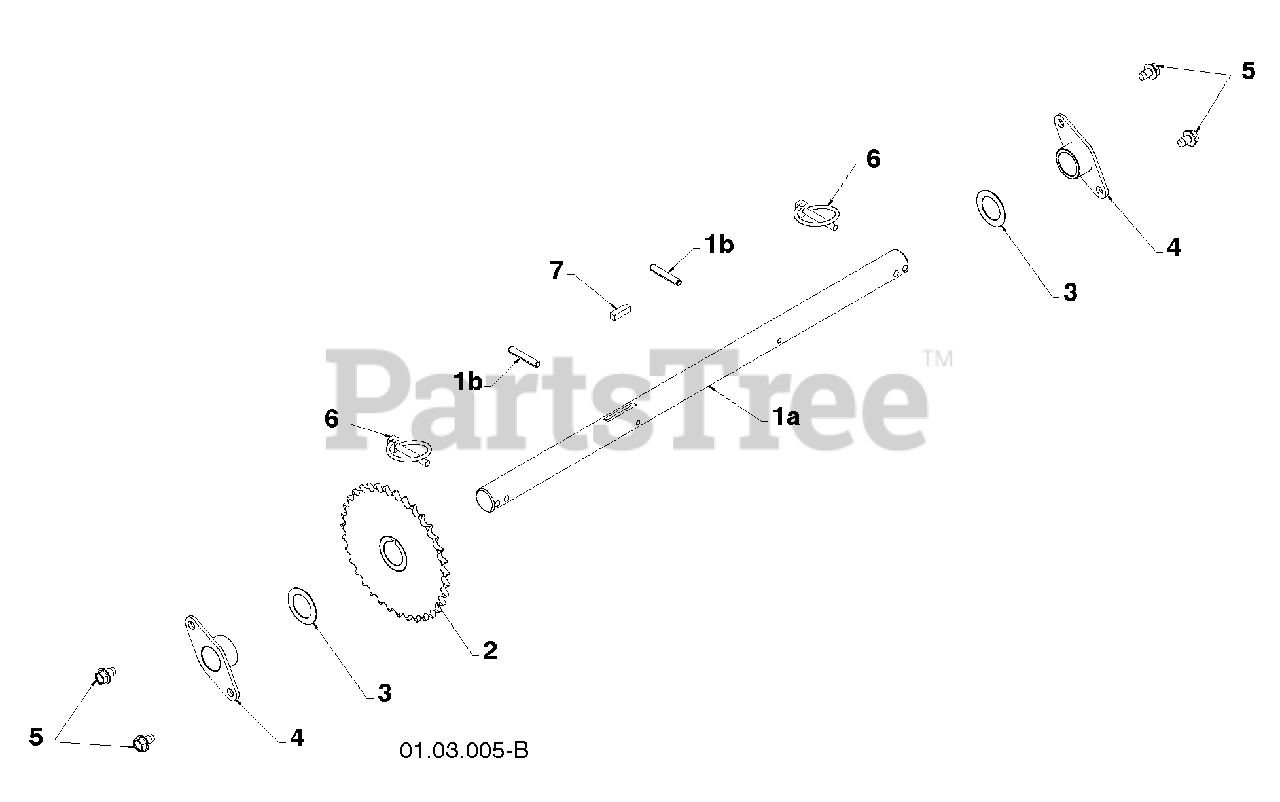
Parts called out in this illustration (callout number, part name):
1	(assy of 1a,1b) AXLE ASSEMBLY
2	SPROCKET
3	THRUST WASHER
4	BEARING
5	BOLT 5/16-18 X .500
6	CLIK PIN
7	SQUARE KEY
